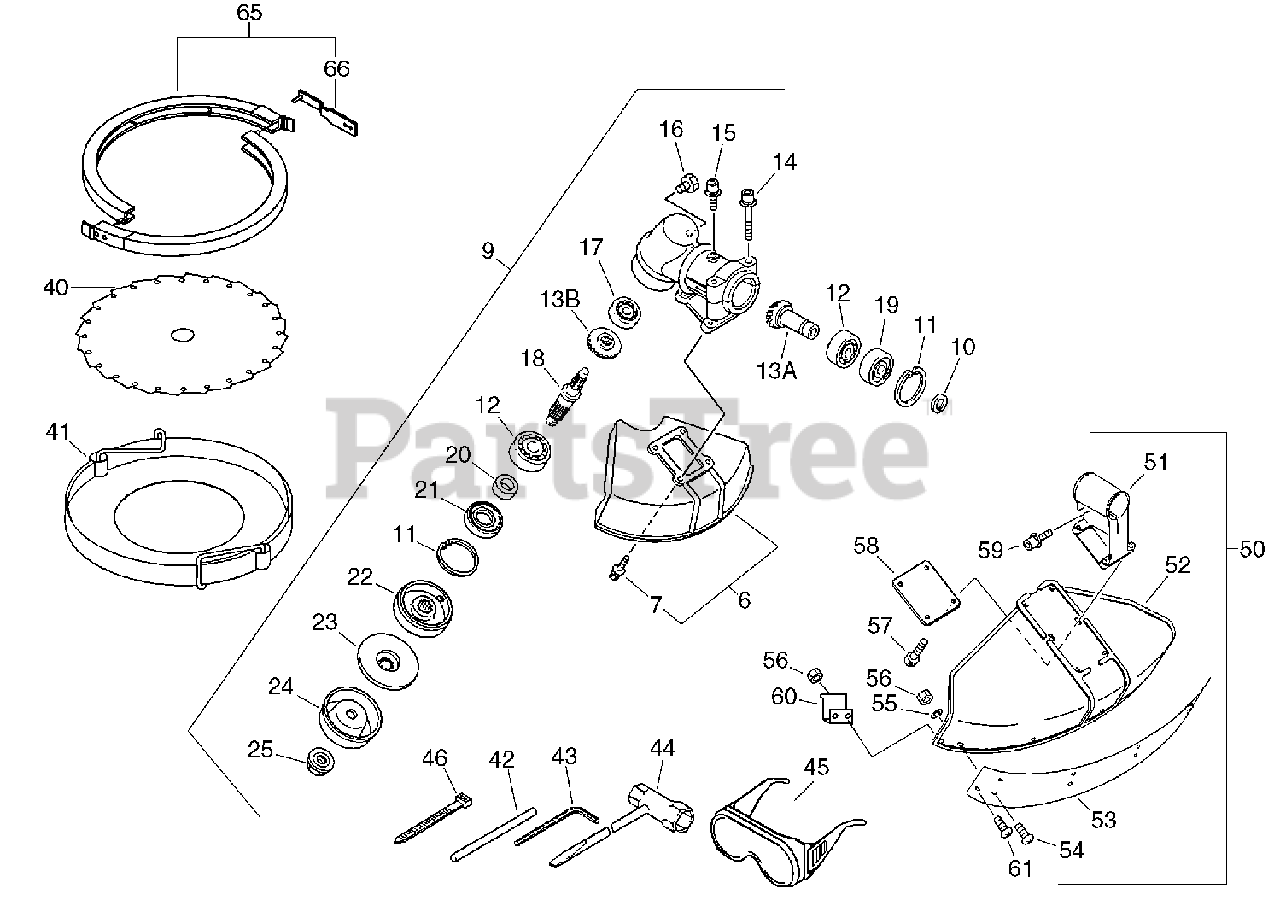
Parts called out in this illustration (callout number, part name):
6	DEBRIS SHIELD KIT
7	BOLT 5×20
9	GEAR CASE HOUSING ASSY
10	RING, RETAINING 15
11	RING, SNAP 35
12	BEARING, BALL 6202
13	GEAR SET
14	BOLT M5×35
15	BOLT 5×14
16	BOLT M8×8
17	BEARING, BALL 6001
18	GEAR, SHAFT
19	BEARING, BALL 6202
21	SEAL, OIL
22	PLATE, ADAPTOR - LOWER
23	PLATE, ADAPTOR - UPPER
25	NUT, LOCK
41	COVER - GRAY
42	TOOL, LOCKING 5×120 MM
43	WRENCH, ALLEN 4 MM
44	T-WRENCH 17x-19 L200
45	GLASSES, SAFETY
46	STRAP, TIE
